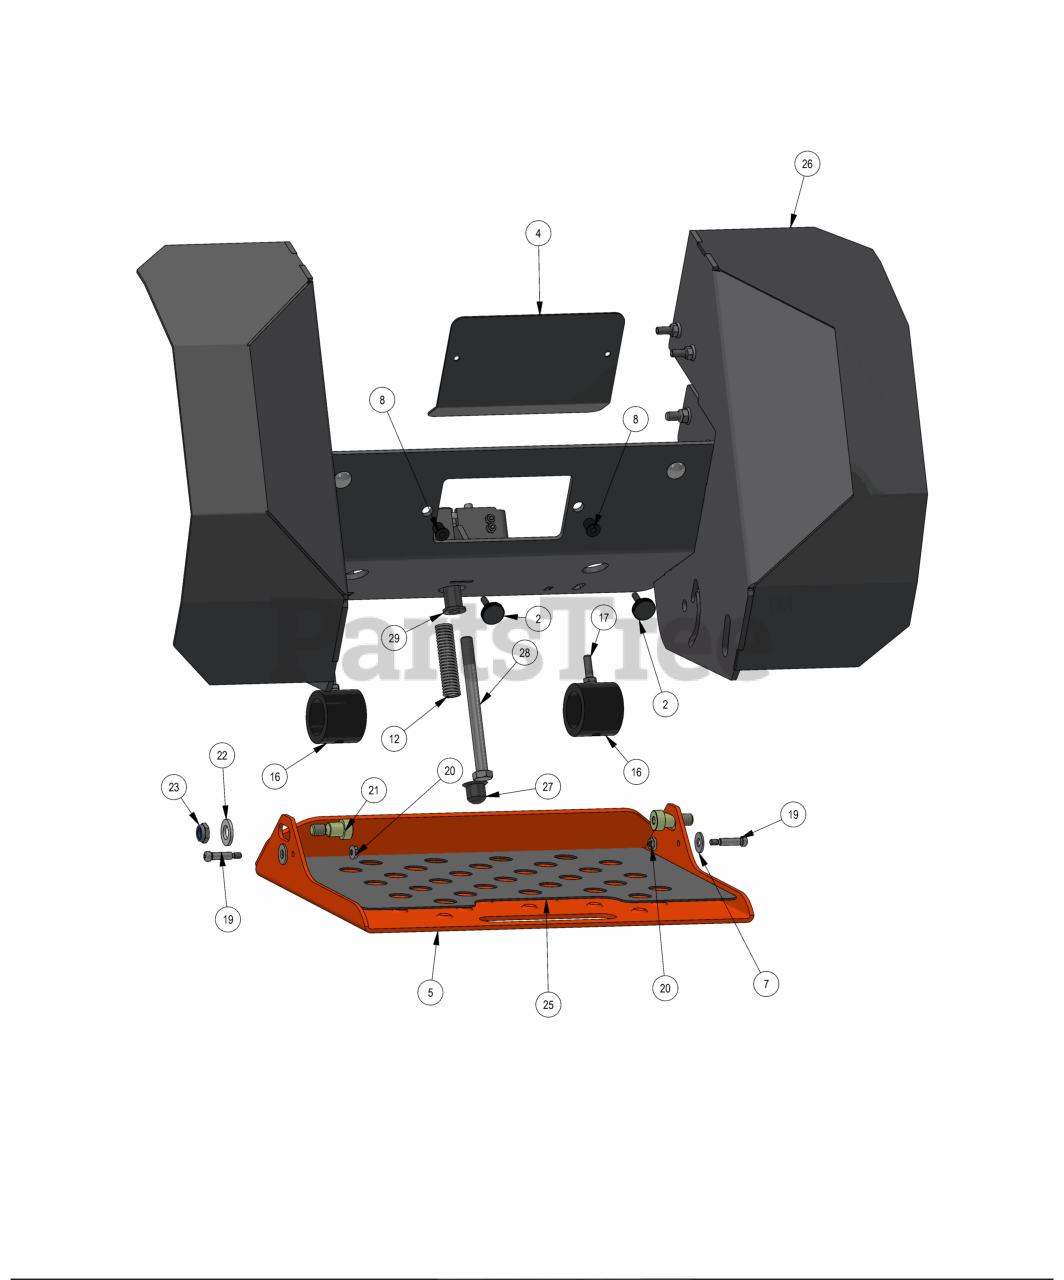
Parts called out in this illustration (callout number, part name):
1	MZ Deck Idler Spacer
2	1/4"-20 x 3/4" Knurled Thumb Screw
3	safety Switch
4	2019 Stand On Access Panel Plate Black Part
5	2020 36" Revolt Platform Plate-Powdercoated
6	10-24 NYLON INSERT LOCKNUT ZINC
7	5/16 USS FLAT WASHER (7/8 OD) ZINC
8	3326 Wellnut (1/4-20 x 5/18")
9	3/8" Nylock Flange Nut
10	3/8-16 X 1-1/4 CARRIAGE BOLT ZINC
11	10-24 X 3/4 BUTTON SOCKET CAP SCREW 18-8 STAINLESS STEEL
12	Rider Presence Spring 9657K145
13	1/2-13 HEX SERRATED FLANGE NUT HARD/ZINC
14	5/16" Nylock Flange Nut Zinc
15	5/16-18 X 1-1/4 CARRIAGE BOLT ZINC
16	2019 Revolt Platform Dampener
17	5/16-18 X 1 HEX CAP SCREW (GR.5) ZINC
18	5/16" Flange Nut
19	Steel Shoulder Screw 1/4"-20 x 7/8" Diameter 5/16"
20	1/4-20 HEX SERRATED FLANGE NUT HARD/ZINC
21	5/8'' x 5/8'' Shoulder Bolt
22	.630 ID Plastic Washer
23	1/2" Nylcock Nut (1/2 Jam)
24	3/8-16 X 1-1/4 HEX CAP SCREW (GR.5) ZINC
25	Grip Tape for 026-0158-00
26	2023 36 Platform Support
27	Hex Nut Cap
28	1/2-13 X 6 HEX CAP SCREW (GR.5) ZINC
29	.504 ID X .740 OD X 1.625 LGTH SLEEVE WASHER NYLON
